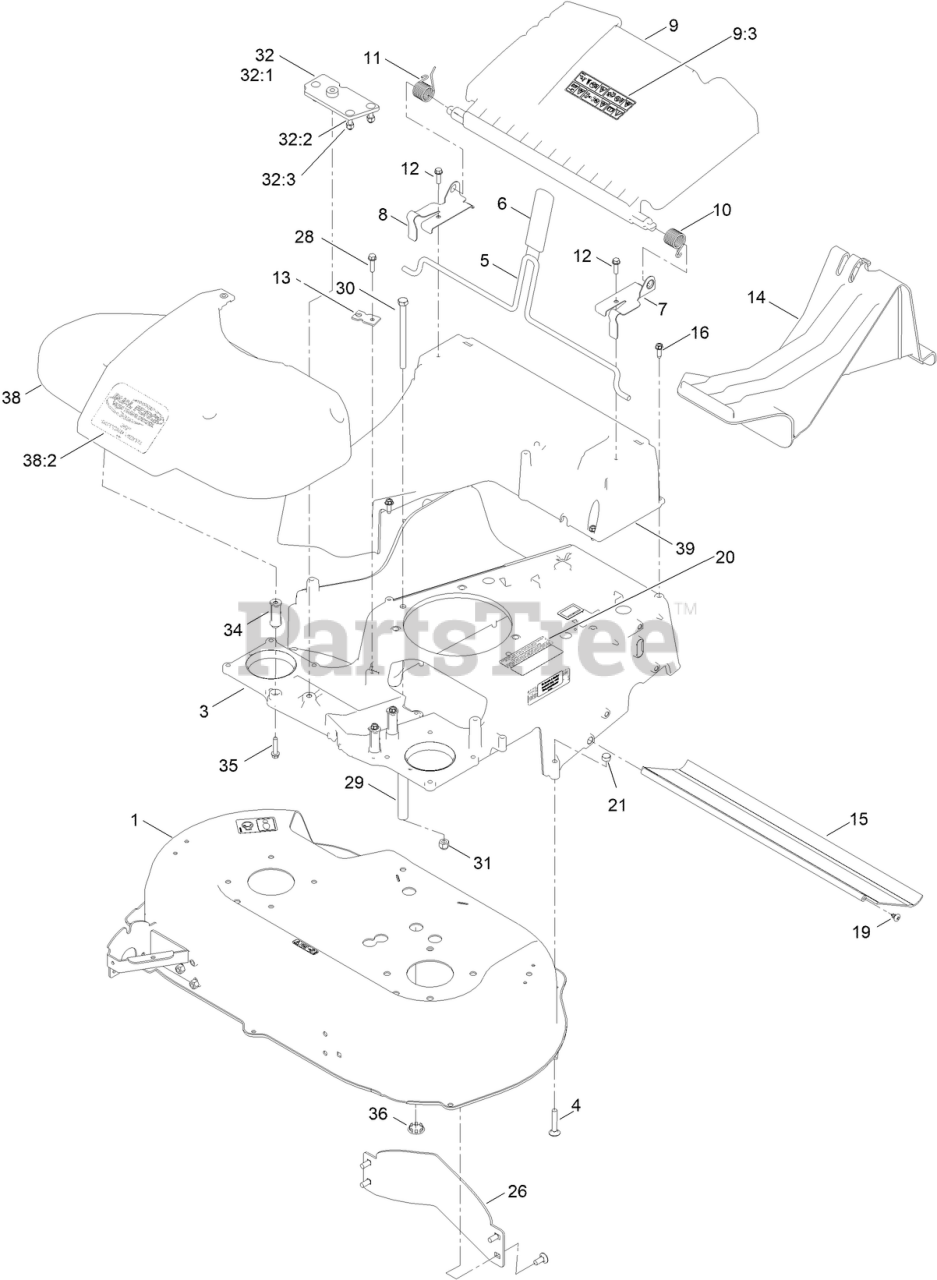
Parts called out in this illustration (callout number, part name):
1	HOUSING ASM
3	FRAME-30"
4	BOLT-CAR
5	ROD-RELEASE, HANDLE
6	GRIP-LEVER
7	BRACKET-DOOR, LH
8	BRACKET-DOOR, RH
9	REAR DEFLECTOR ASM
9:3	DECAL-WARNING
10	SPRING-TORSION
11	SPRING-TORSION
12	SCREW-HWH
13	BRACKET-CABLE, TRACTION
14	PLUG-MULCH
15	SHIELD-TRAILING
16	SCREW-HWHTF
19	SCREW-THD
20	DECAL-ARRESTOR, SPARK
21	NUT-LOCK, NI
26	BAFFLE-CONTROL
28	SCREW-HWHTF
29	SPACER-SHIELD
30	SCREW-HH
31	NUT-HEX
32	FRAME PLATE KIT
32:1	PLATE-FRAME
32:2	SCREW-CARR
32:3	NUT-LOCK, NI
34	SPACER-FRAME, 30 IN.
35	SCREW-HWHTF
36	PLUG-BUTTON
38	BELT COVER ASM
38:2	DECAL-COVER, BELT
